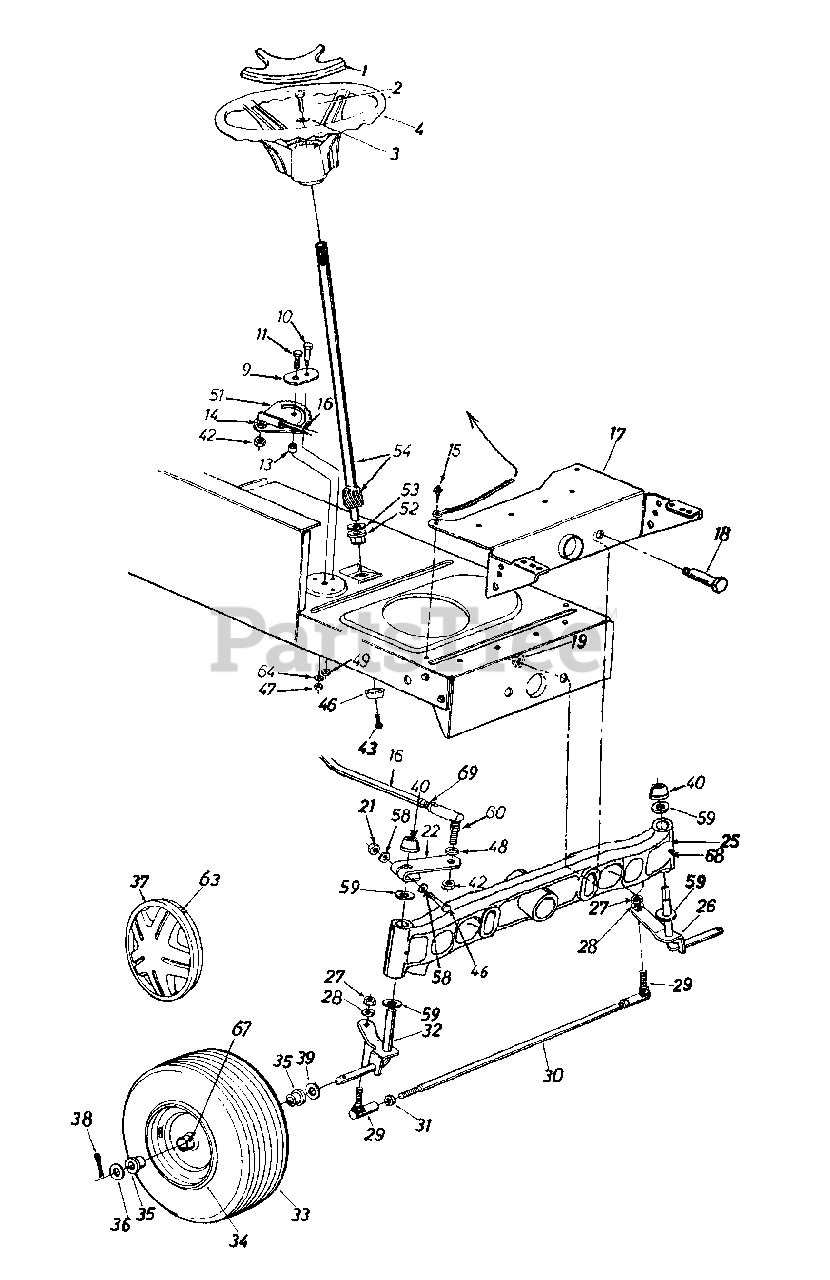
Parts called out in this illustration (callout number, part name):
1	Steering Wheel Cap
2	Hex Bolt 5/16-18 x 1" Lg.
3	Belleville Wash. .345" I.D.
4	Steering Wheel
9	Retainer Plate
10	Shld Bolt .437" x .35" Lg. - 5/16-18
11	Hex Bolt 3/8-24 x 1.0" Lg. (Grade 5)
13	Spacer .380" I.D. x .625" O.D. x .227
14	L-Wash. 3/8" I.D. (H.D.)
15	Hex Wash. Hd. Self-Tap Scr.
16	Steering Drag Link
18	Shoulder Bolt .498" Dia. x 2.04"
19	Flanged Hex Nut 3/8-16 Thd.
21	Hex L-Nut 5/16-24 Thd.
22	Steering Arm Front Axle
25	Pivot Bar Ass'y.
26	Front Axle Ass'y. - L.H.
27	Hex Nut 3/8-24 Thd.
28	L-Wash. 3/8" I.D.
29	Ball Joint 3/8-24 Thd.
31	Hex Jam Nut 3/8-24 Thd.
32	Front Axle Ass'y. - R.H.
36	Fl-Wash. .635" I.D. x 1.59" O.D.
38	Cotter Pin 1/8" Dia. x 1.25"
39	Fl-Wash. .640" I.D. x 1.24" O.D.
40	Push Cap 5/8" Dia. Rod
42	Hex Jam Nut 3/8-24 Thd.
43	Torx Bolt 5/16-18 x .63" Lg.
46	Cap 1.25 x .16
47	Hex Cent. L-Nut 3/8-24 Thd.
49	Hex Cent. L-Nut 5/16-18 Thd.
51	Steering Gear Segment
52	Hex. Flg. Brg. 5/8" I.D.
53	Fl-Wash. (Hardened)
54	Steering Shaft
58	Wave-Wash. .32" I.D. x .62" O.D.
59	Fl-Wash. (Hardened)
60	Drag Link Ball Joint 3/8-24 Thd.
63	Spring Clip
64	Bell-Wash. .39" I.D. x 1.38" O.D.
67	Grease Fitting
68	Grease Fitting
69	Hex Jam Nut 7/16-20
